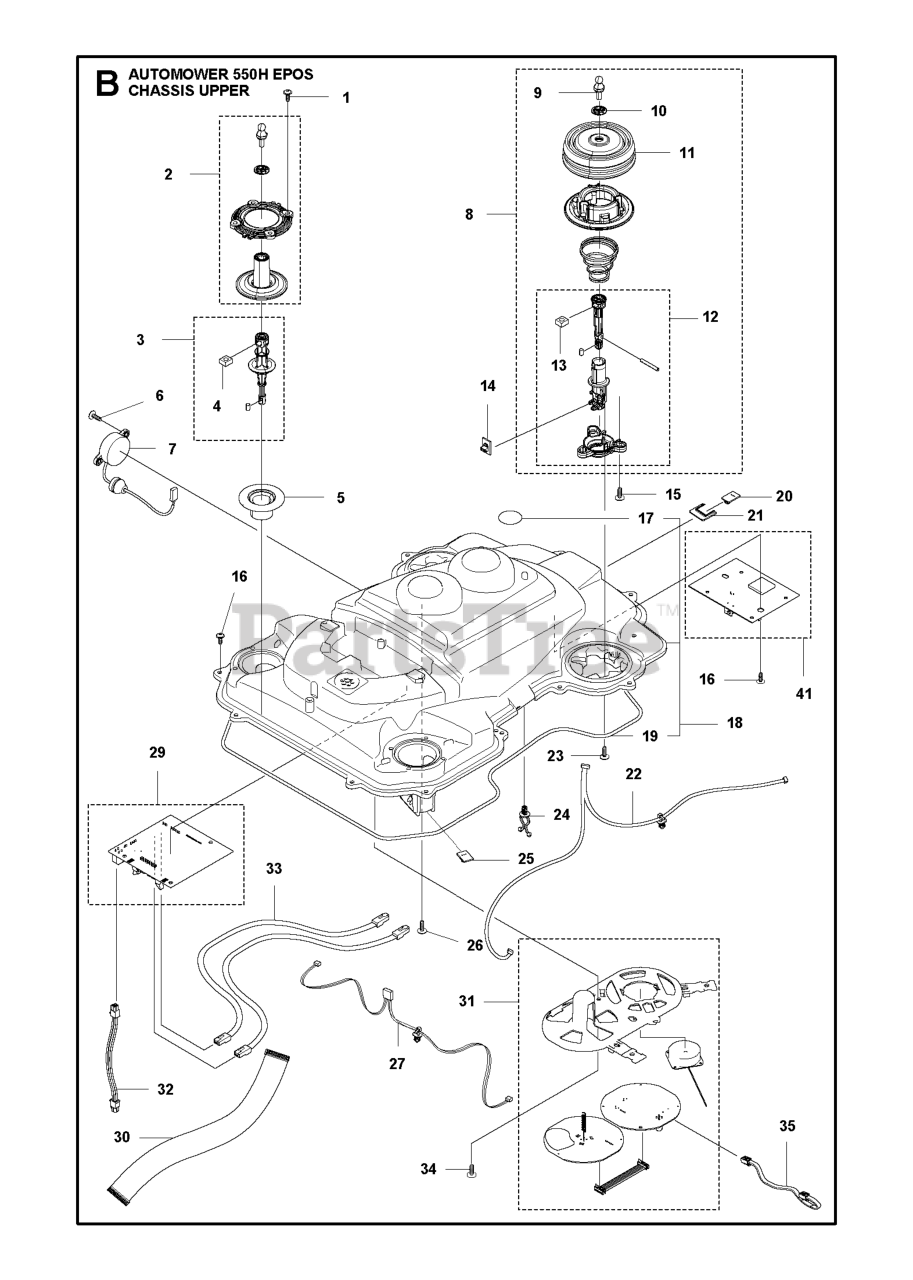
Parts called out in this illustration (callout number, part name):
1	SCREW ITXPANT
2	JOYSTICK KIT REAR
3	JOYSTICK KIT REAR
4	NUT
5	MOVEMENT LIMITER
6	SCREW 14MM
7	BUZZER ASSY
8	JOYSTICK KIT
9	STUD SNAPLOC
10	WASHER JOYSTICK
11	BELLOWS LIFT-COLLISION
12	JOYSTICK KIT
13	NUT
14	PRINTED CIRCUIT ASSY PCBA LIFT
15	SCREW 14MM
16	SCREW ITXPANT
17	KIT AIR FILTER KIT 305 - 10 PC
18	CHASSIS KIT UPPER 550 EPOS / 5
19	SEALING STRIP
20	PRINTED CIRCUIT ASSY COLLISION
21	CLIP COLLISION BOARD
22	WIRING ASSY LIFT SENSOR L1=670
23	SCREW ITXPANT
24	HOLDER TWIST LOCK
25	PRINTED CIRCUIT ASSY COLLISION
26	SCREW ITXPANT
27	1OOM KIT COLLISION SENSOR
29	PRINTED CIRCUIT ASSY PCBA APPL
30	LOOM MMI
31	HOLDER ASSY ANTENNA MODULE 915
32	WIRING ASSY HMI CABLE 4P L=33
33	WIRING ASSY MODULAR JACK 6/6 R
34	SCREW 14MM
35	Wires
